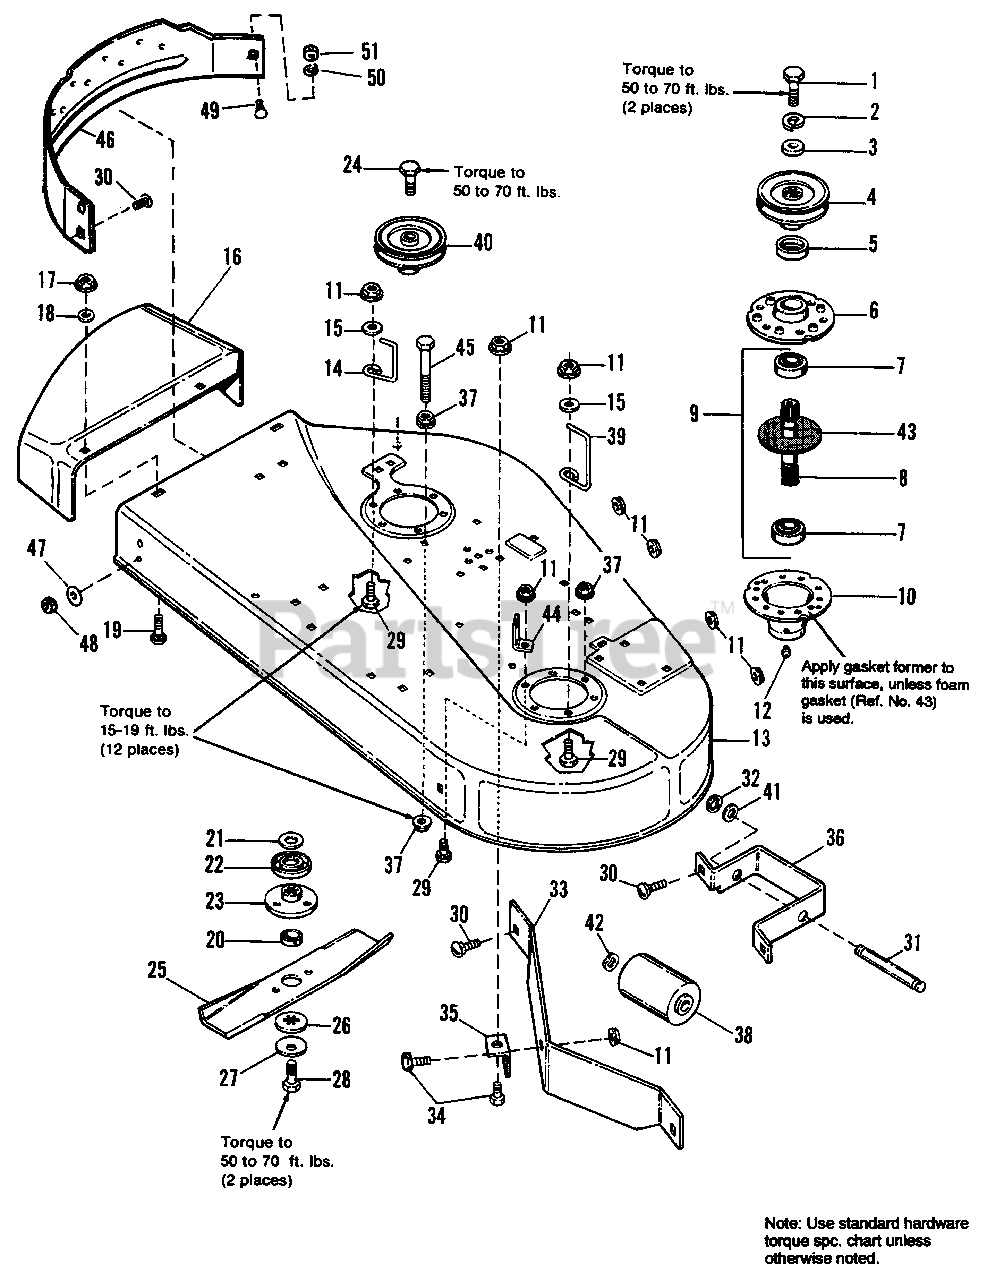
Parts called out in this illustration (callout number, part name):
1	CAPSCREW, Hex Hd., 7/16-14 x 3-1/2
2	LOCKWASHER, 7/16
3	WASHER, 29/64 x 1-1/4 x 1/4
4	PULLEY ASSY.
5	SHIELD, Bearing Upper, Arbor
6	ARBOR HOUSING, Top
8	SHAFT, Arbor (Incl. Ref. No. 20)
9	SHAFT & BEARING ASSY. (Incl. Ref. Nos. 7 (Qty. 2), 8, 20 & 43)
10	ARBOR HOUSING ASSY., Bottom (Incl. Ref. No. 12)
11	NUT, Hex, Flange, Whizlock, 5/16-18
12	GREASE FITTING
13	HOUSING, 38", ORANGE (Incl. Safety Decals)
13	HOUSING, 36", BLACK (Incl. Safety Decals)
15	WASHER, 11/32
16	DEFLECTOR, ORANGE
17	NUT, Hex, Flange, Whizlock, 3/8-16
18	WASHER, 13/32
19	CARRIAGE BOLT, 3/8-16 x 3/4
20	COLLAR, Arbor
21	WASHER, Shim
22	SHIELD, Grass
23	ADAPTOR, Blade
24	CAPSCREW, Hex Hd., 7/16-14 x 2-3/4
26	WASHER, Spline
27	WASHER, Cup
28	CAPSCREW, Hex Hd., 7/16-14 x 1
29	SCREW, Hex, Wash. Hd., Taptite, 5/16-18 x 1
30	CARRIAGE BOLT, 5/16-18 x 3/4
31	SHAFT, Roller, Center
32	E-RING
33	BAFFLE
34	CAPSCREW, Hex Hd., 5/16-18 x 3/4
35	BRACKET, Mower
36	BRACKET, Center, Roller
37	NUT, Hex, Flange, Whizlock, 5/16-18
40	PULLEY ASSY.
41	WASHER, Nylon
42	WASHER, Wave
43	GASKET, Foam
44	BRACKET, Lift
45	CAPSCREW, Hex Hd., 5/16-18 x 3-1/2
46	BAFFLE, Mulching (See Note below)
47	LOCKWSHER, 5/16
48	NUT, Hex, 5/16-18
49	CARRIAGE BOLT, 1/4-20 x 3/4
50	LOCKWASHER, 1/4
51	NUT, Hex, 1/4-20
